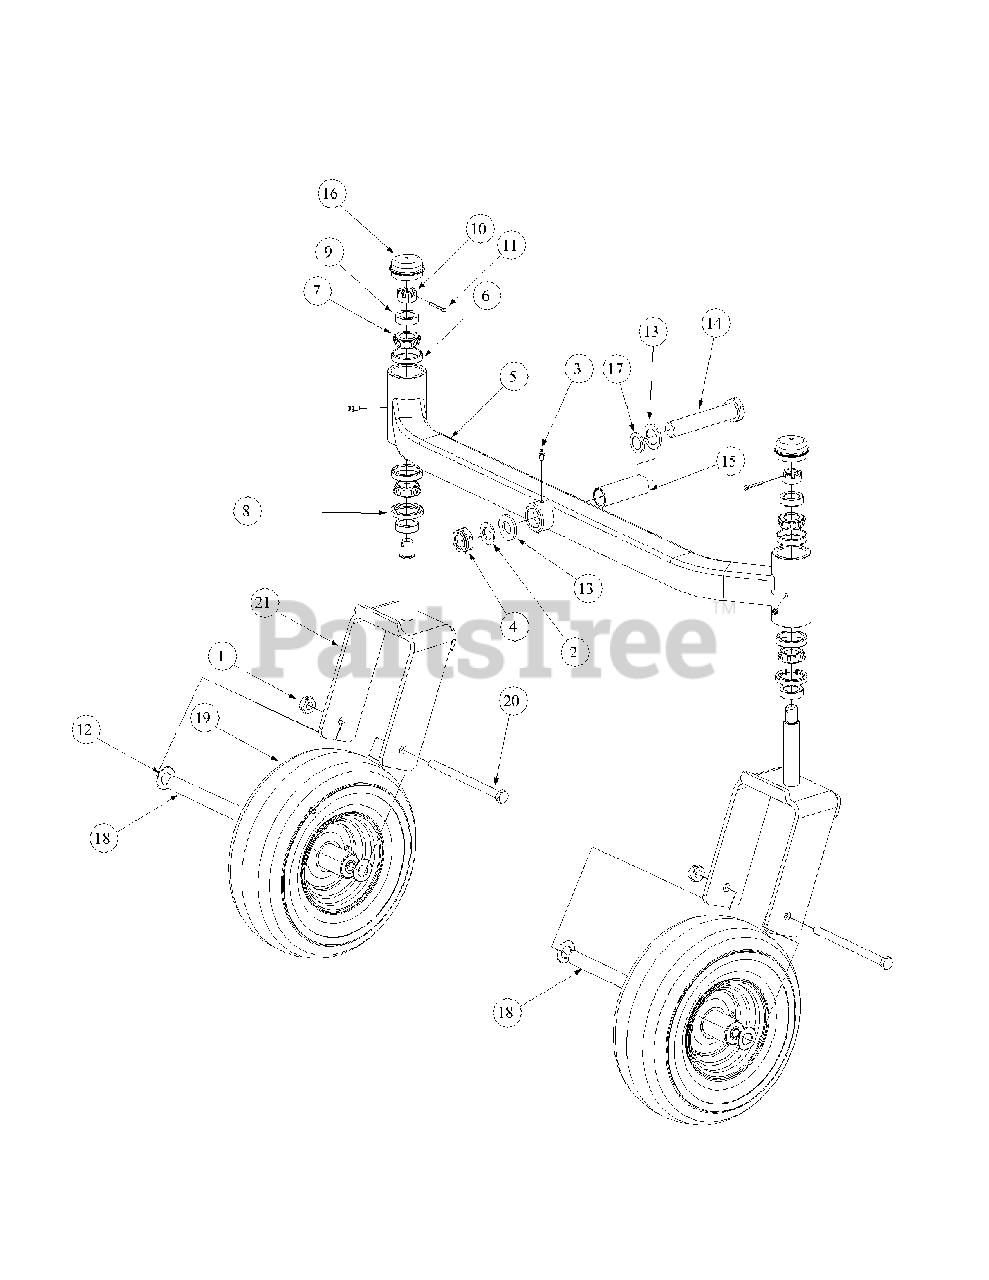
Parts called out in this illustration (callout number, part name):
1	Nut, 1/2-20, Center Lock
2	Special Washer
3	Grease Fitting
4	Nut, Jam, 1.0-14, Insert Lock
5	Front Axle Assembly
6	Cup Bearing
7	Bearing Cone
8	Seal
9	Ring Seal
10	Slotted Nut, 3/4-16
11	Cotter Pin, 5/32, 1.25
12	Spacer, .812 ID x .218 Long
13	Bell Washer, 1.25 ID
14	Hex Cap Screw, 1-14 x 5.0
15	Spacer, 1.005 ID x 1.25 OD x 3.6
16	Grease Cap, 1.986 OD
17	Flat Washer, 1.25 ID
18	Wheel Spacer
19	Wheel, 13 x 6.50 x 6, White Includes;
19	Retainer Flange
19	Roller Bearing
20	HHCS, 1/2-20, 7.50
21	Yoke, Caster Wheel
